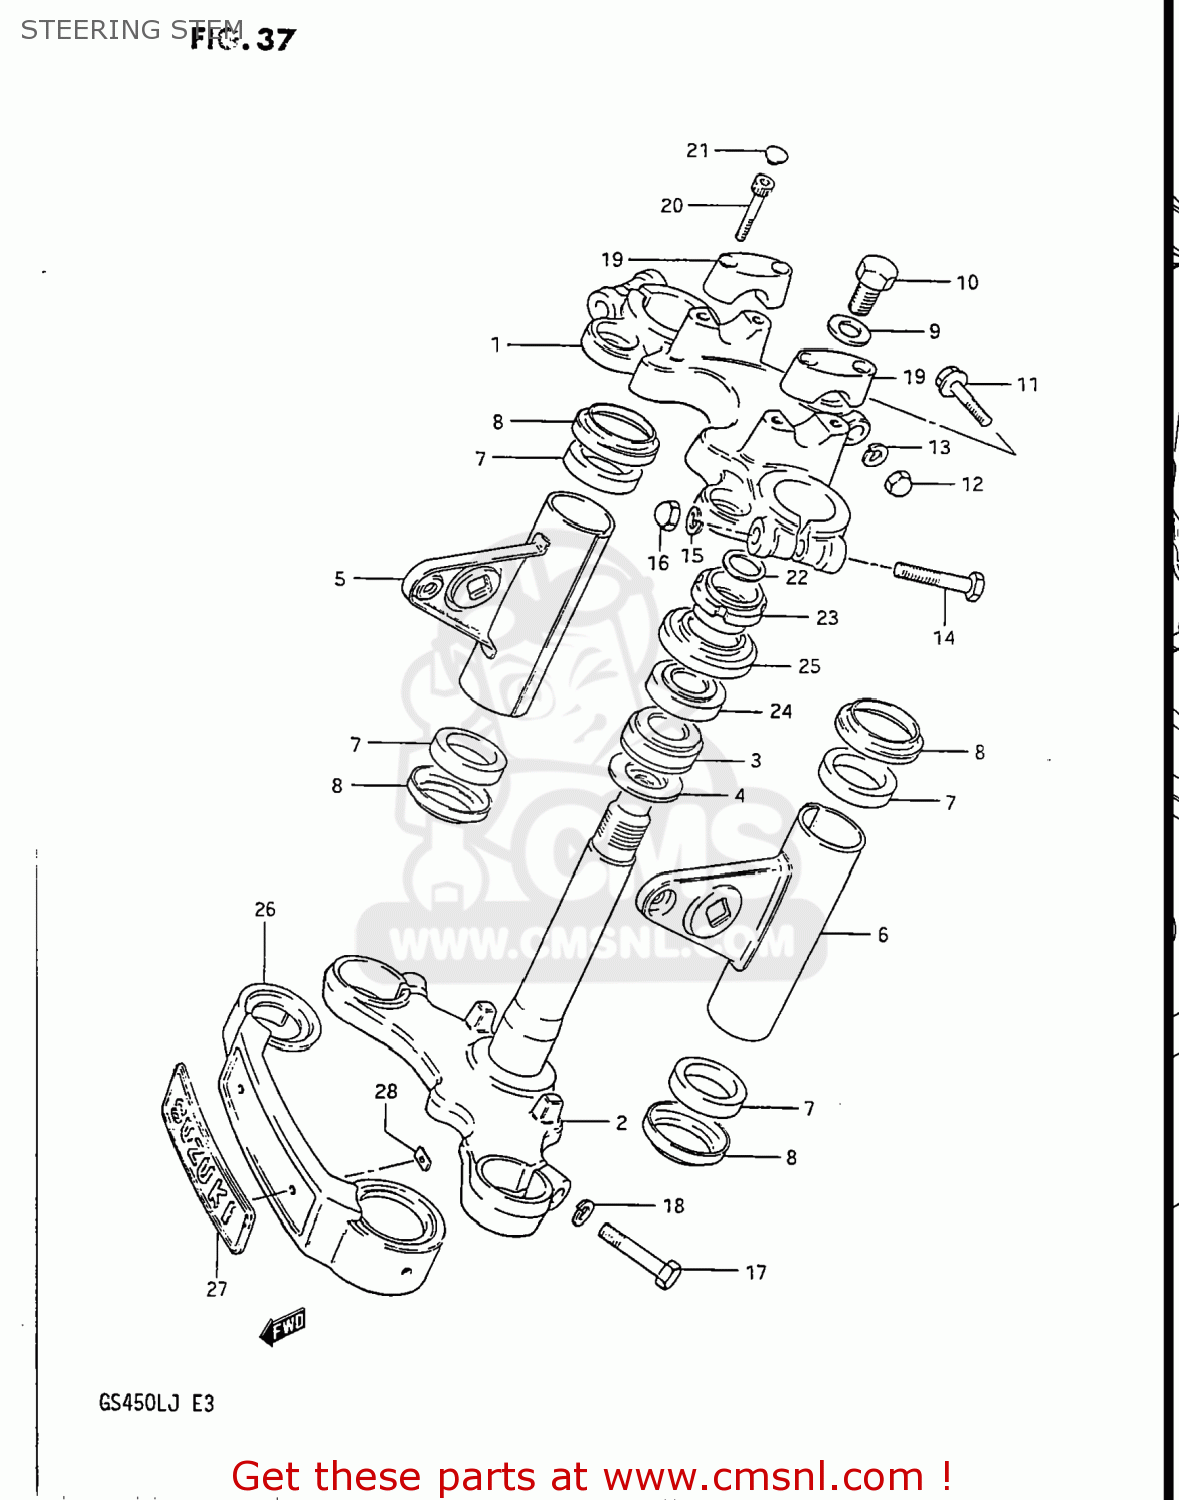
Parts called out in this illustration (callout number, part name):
1	HEAD,STEERING STEM
2	STEM,STEERING
3	BEARING
4	WASHER,THRUST
5	BRACKET,HEADLAMP,RIGHT
6	BRACKET,HEADLAMP,LEFT
7	CUSHION,HEADLAMP BRACKET
8	CAP,HEADLAMP BRACKET
9	WASHER (12.5X26X1.6)
10	BOLT 12X20
11	BOLT, UPPER
12	NUT,M8X1.25X12
13	WASHER,LOCK,8.
14	BOLT
15	WASHER,LOCK
16	NUT
17	BOLT
18	WASHER,LOCK
19	HOLDER,HANDLEBAR(BLACK)
20	BOLT, REAR (8X30)
21	CAP(OD:14.5)
22	WASHER(18.5X24X1)
23	NUT,STEERING STEM
24	TAPER,ROLLER BEARING
25	DUST SEAL,STEERING UPR
26	COVER,FRONT FORK
27	EMBLEM,FR FORK COVER
28	NUT
